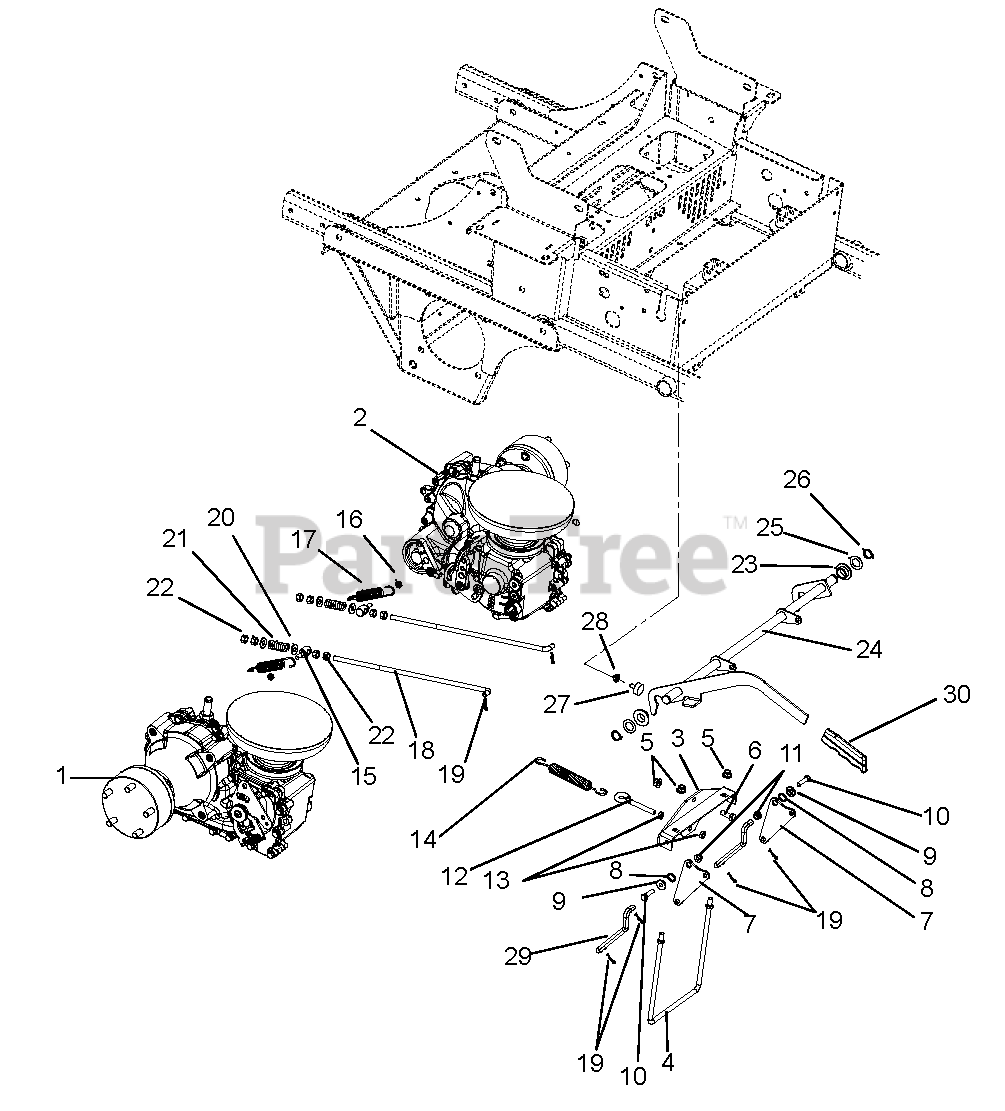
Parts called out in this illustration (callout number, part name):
1	Transmission, Right Hand HG ZT-5400
2	Transmission, Left Hand HG ZT-5400
3	Weldment, Spring Anchor Bracket
4	Rod, Brake Mounting
5	Nut, Locking Nylon-Flange .38-16 YWZC
6	Bolt, Hex .38-16 x 1.00 GR5 YWZC
7	Plate, Brake Pivot
8	Wave Washer .531 x .781 x .125FH
9	Bushing, Flange .32 x .500 x .344 x .880
10	Bolt, Hex .31-18 x 1.25 GR5 YWZC
11	Nut, Locking Nylon-Flange .31-18 YWZC
12	Bolt, Eye .375-16 x 2.50 YWZC
13	Nut, Hex-JAM .375-16 YWZC
14	Spring, Extension
15	Trunnion, .38-16
16	Nut, Locking Center-Jam .31-18 YWZC
17	Spring, Tension .105 x .85 x 5.00 WLD 40
18	Rod, Brake Adjustment
19	Pin, Hair
20	Washer, Flat Steel.38 x .875 x .083 YWZC
21	Spring, Compression .142 x .710 x 1.75
22	Nut, Hex .38-16 YWZC
23	Bushing, Flange .762 x 1.48 x .44 NYL
24	Weldment, Brake Interlock
25	Washer, Hardened Thrust .758 x 1.23 x .031
26	Ring, Retaining-EXT .689 x .078
27	Bumper, Rubber
28	Nut, Spin Lock-Flange .312-18 YWZC
29	Linkage, Brake Actuating
30	Grip, Parking Brake (Yellow)
